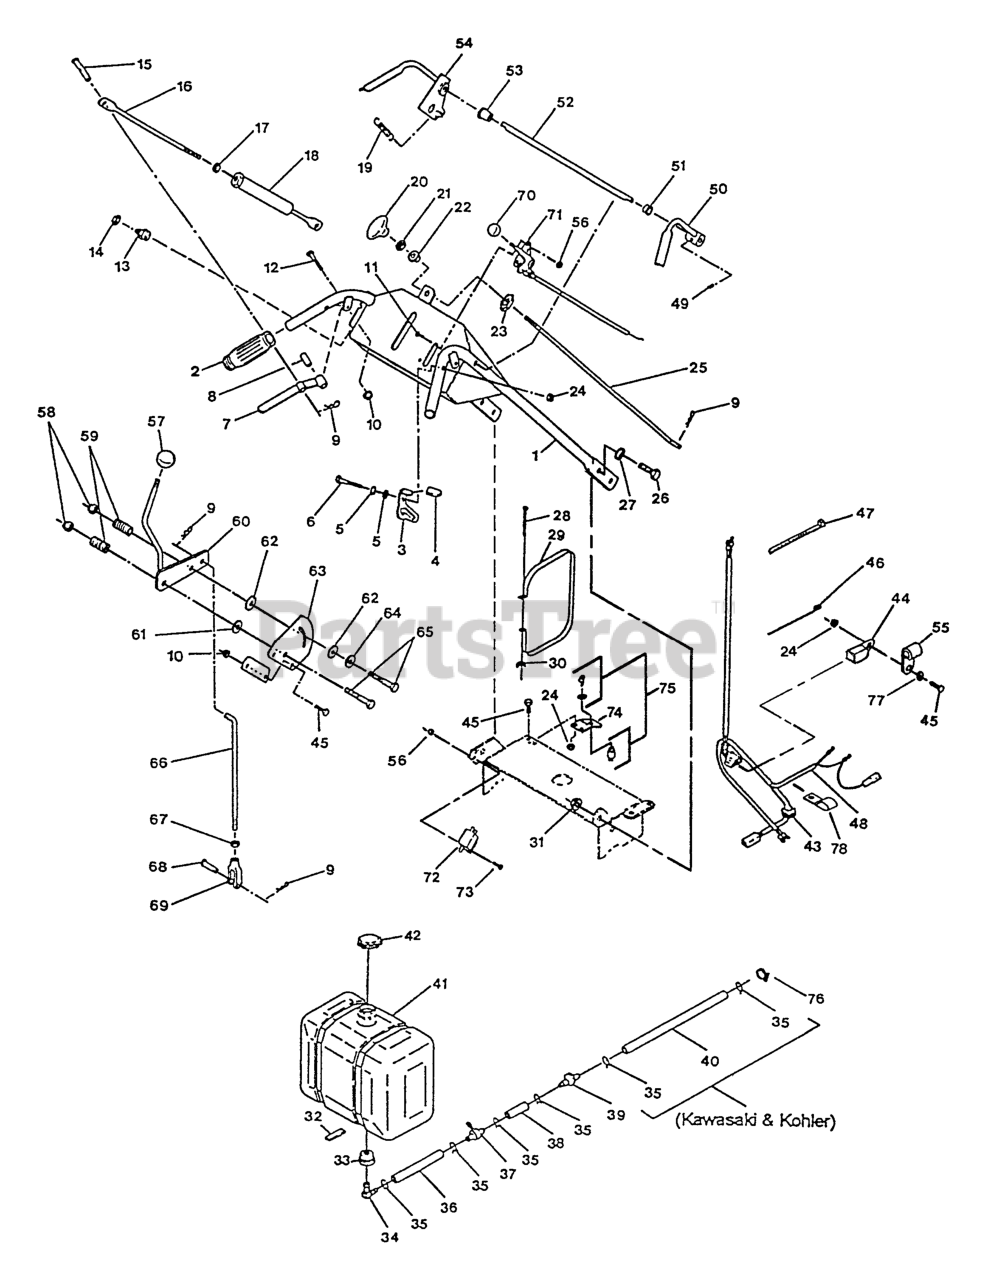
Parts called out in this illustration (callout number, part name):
3	RH LATCH W/GRIP
4	GRIP-LATCH
5	WASHER-SPRING
8	BUSHING-LEVER, DRIVE
9	PIN-COTTER
11	BOLT-CARR
13	SWITCH,OPERATOR CNTRL
15	PIN-CLEVIS
16	ROD,DRIVE LEVER LINKAGE
18	WLD,HOUSING
19	SPRING-EXTENSION
20	KNOB-PUSH / PULL
22	BEARING-NYLON
23	NUT-PUSH
25	LINKAGE-BLADE
28	SCRW,MACH CRPH
30	WINGNUT
32	PAD,PLASTIC TANK
34	ELBOW-TANK, FUEL
36	HOSE-FUEL
37	VALVE-FUEL
38	HOSE-LINE, FUEL
40	HOSE-LINE, FUEL
42	CAP-FUEL
43	GROMMET
44	MODULE-INTERLOCK
46	TIE-CABLE
47	TIE-PLASTIC
49	SCREW-SET
51	BUSHING-NYLON
52	ROD,CONNECTING
53	BUSHING,FLANGED
55	CLIP-LOOM
57	KNOB-BALL
59	SPRING-COMPRESSION
62	WASHER-FRICTION
63	PLATE-LEVER, SHIFTER
64	WASHER-FRICTION
66	ROD,SPEED CONTROL PLTD
68	PIN-CLEVIS
69	YOKE-ADJUSTABLE
70	KNOB-BALL
71	CABLE,THROTTLE CONTROL
72	SWITCH-OPEN, NORMALLY
75	SWITCH & KEY (INCLUDES NU
76	CLAMP-HOSE
